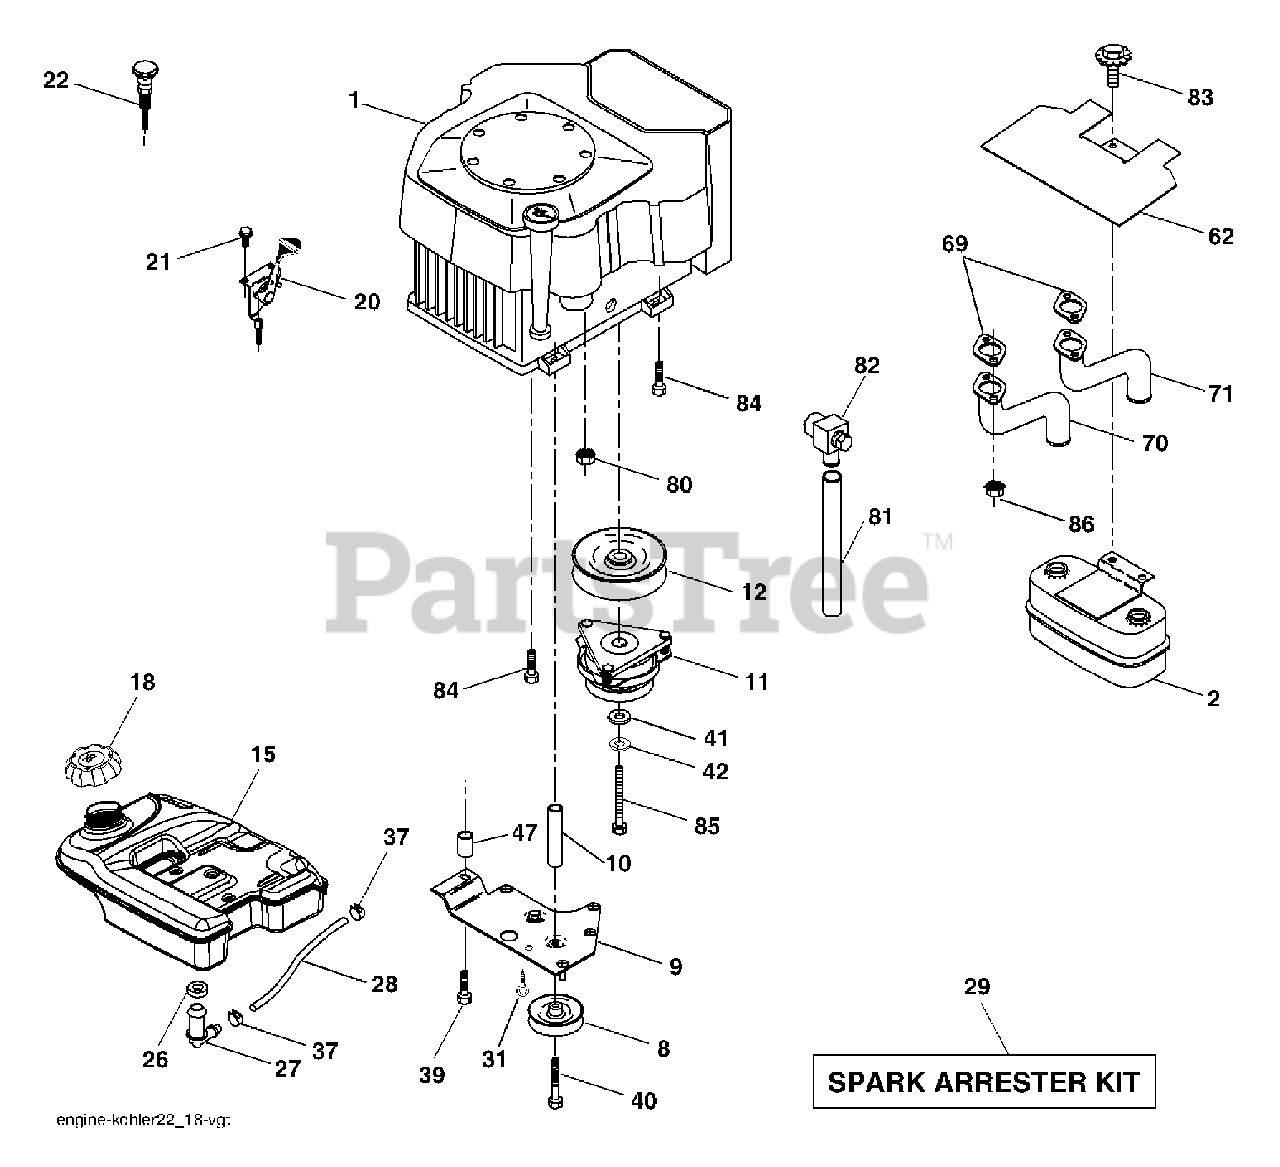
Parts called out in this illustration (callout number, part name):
2	Muffler Side
8	Pulley V-Idler
9	Keeper Asm. Belt Engine VGT
11	Clutch Electric
12	Pulley Engine VGT Elect Clutch
15	Tank Fuel Rear 5.0
18	Cap Fuel
20	Control Throttle
21	Screw 10 x 3/4 Single Lead Hex
22	Control Choke
26	Bushing
27	Stem Tank Fuel
28	Fuel Line
29	Spark Arrester Kit
31	Clip Push-In Hinged
37	Clamp Hose
39	Screw TT 3/8-16 x 2-1/4 unc
40	Screw TT 3/8-16 x 4 unc
41	Washer 1-1/2 OD X 15/32 ID X .250
42	Washer Lock 7/16
62	Shield Heat Muffler
69	Gasket
70	Tube Exhaust LH
71	Tube Exhaust RH
80	Nut Flange
81	Oil Drain Tube
82	Valve Drain Oil
83	Bolt 5/16-18 unc x 1-3/4 W/Sems
84	Screw 3/8-16 x 1-1/2
85	Bolt Hex 7/16-20 x 3.75 Or. 5
86	Nut Hex Flange Toplock M8-1.25
